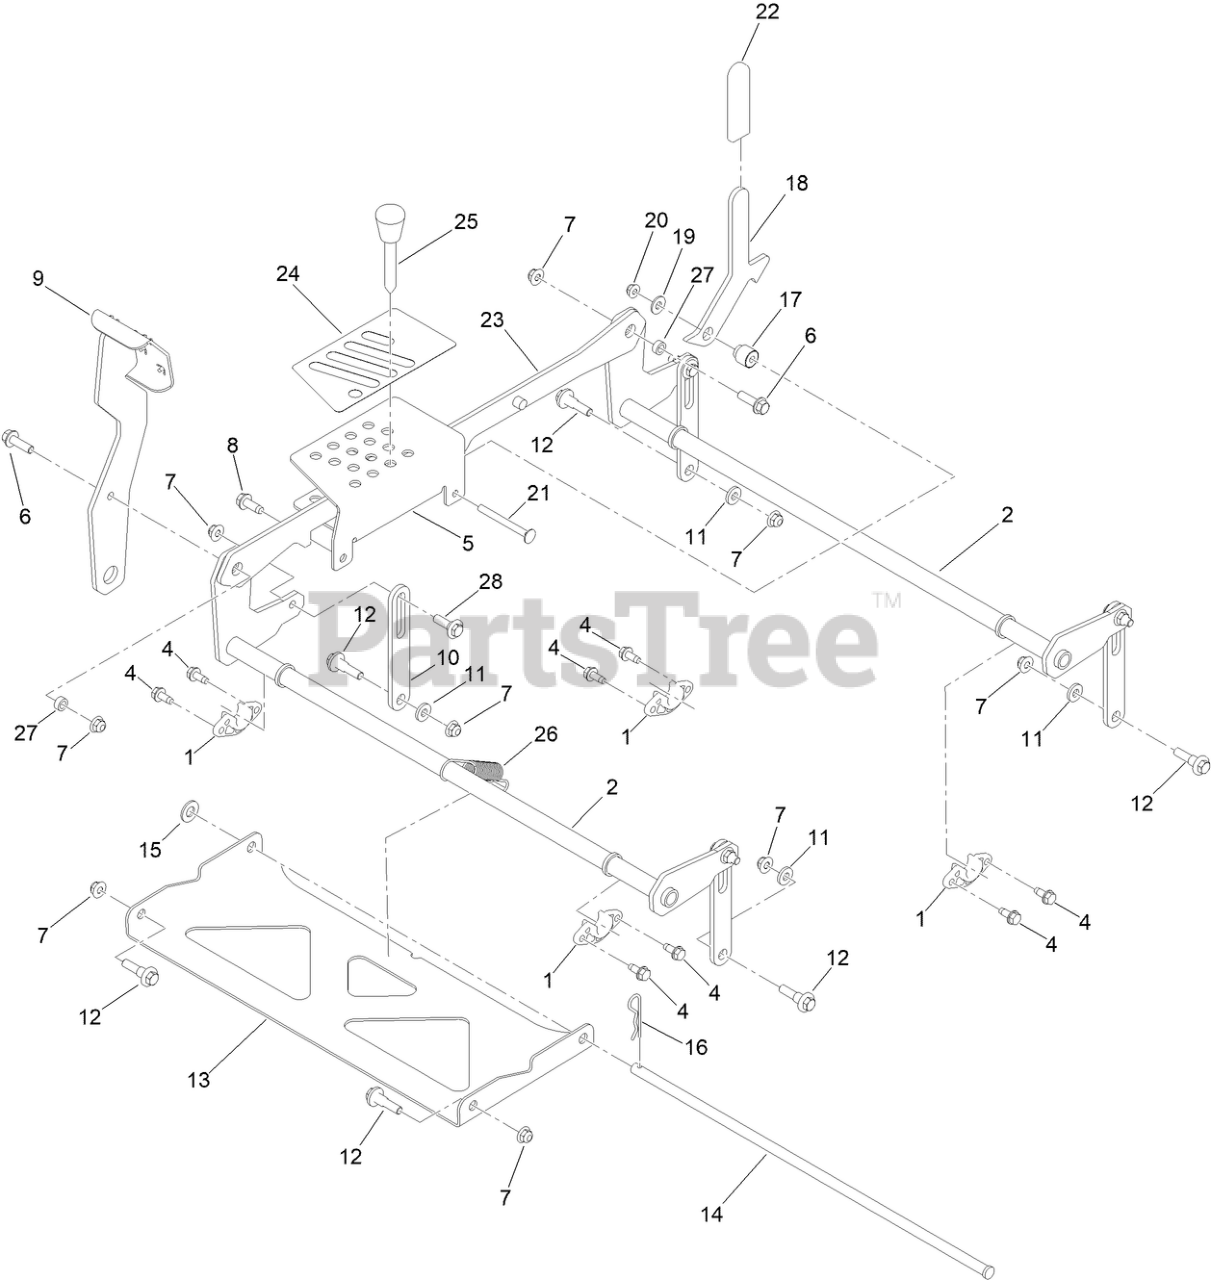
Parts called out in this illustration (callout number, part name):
1	BEARING-FLANGE
2	PIVOT ASM-DECKLIFT [RED]
4	SCREW-HWHTF
5	BRACKET-HOC
6	SCREW-HHF
7	NUT-HF, NI
8	SCREW-HWH
9	PEDAL ASM [RED]
10	LINK-HOC
11	SPACER-HUB, BLOWER
12	BOLT-SHOULDER
13	PAN-DECK PIVOT
14	PIN-DECK
15	WASHER-FLAT
16	PIN-HAIR
17	SPACER-STEPPED
18	PLATE-TRANSPORT LOCK
19	WASHER-PLAIN
20	NUT-HF
21	SCREW-CARR
22	GRIP-HANDLE
23	LINK ASM-HOC [RED]
24	DECAL-HOC
25	HOC PIN ASM
26	SPRING-EXTENSION
27	SPACER
